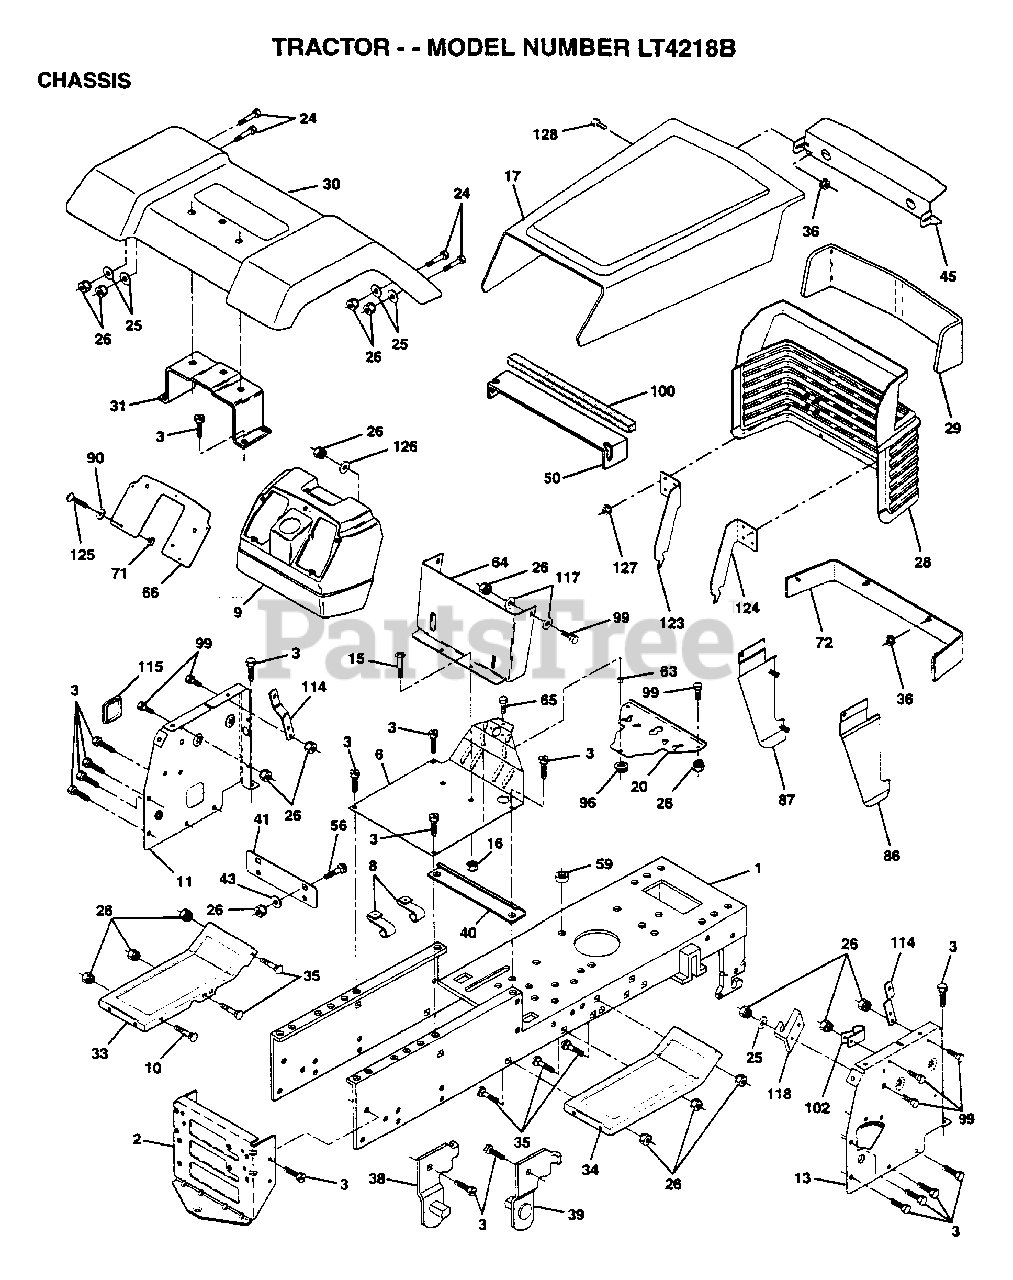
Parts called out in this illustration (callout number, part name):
3	SCREW
8	"CLIP,INSULATOR"
9	DASH.PLASTIC.BLK
11	PANEL.DASH.LH
13	PANEL DASH RH NOT
15	SCREW
16	NUT
17	HOOD/GRILLE ASM
20	PLATE.SUPT.BATTER
24	BOLT
25	WASHER
26	NUT
28	GRILLE ASM WELD
31	BRACKET SUPT FEND
35	BOLT
36	PAL NUT LT
38	BRACKET ASM LH
39	BRACKET ASM RH
40	SPACER FENDER LT
41	PLATE EXTEN FEND
43	WASHER
50	"BAFFLE,HOOD"
56	BOLT
63	SPACER
65	BOLT
66	PLATE DASH SILKSC
71	NUT HXKEP 1/4X20
72	STRAP FENDER ASM
86	PANEL SIDE RH ASM
87	PANEL SIDE LH ASM
90	WASHER PM
96	NUT
99	BOLT
100	FOAM STRIP T
102	CLIP T
114	BRACKET.ASM.SUPT.
115	COVER ACCESS
117	WASHER.SERRATED.
124	BRACKET.PICK.RH
125	SCREW
126	WASHER
127	PAL NUT
128	SCREW SPECIAL
